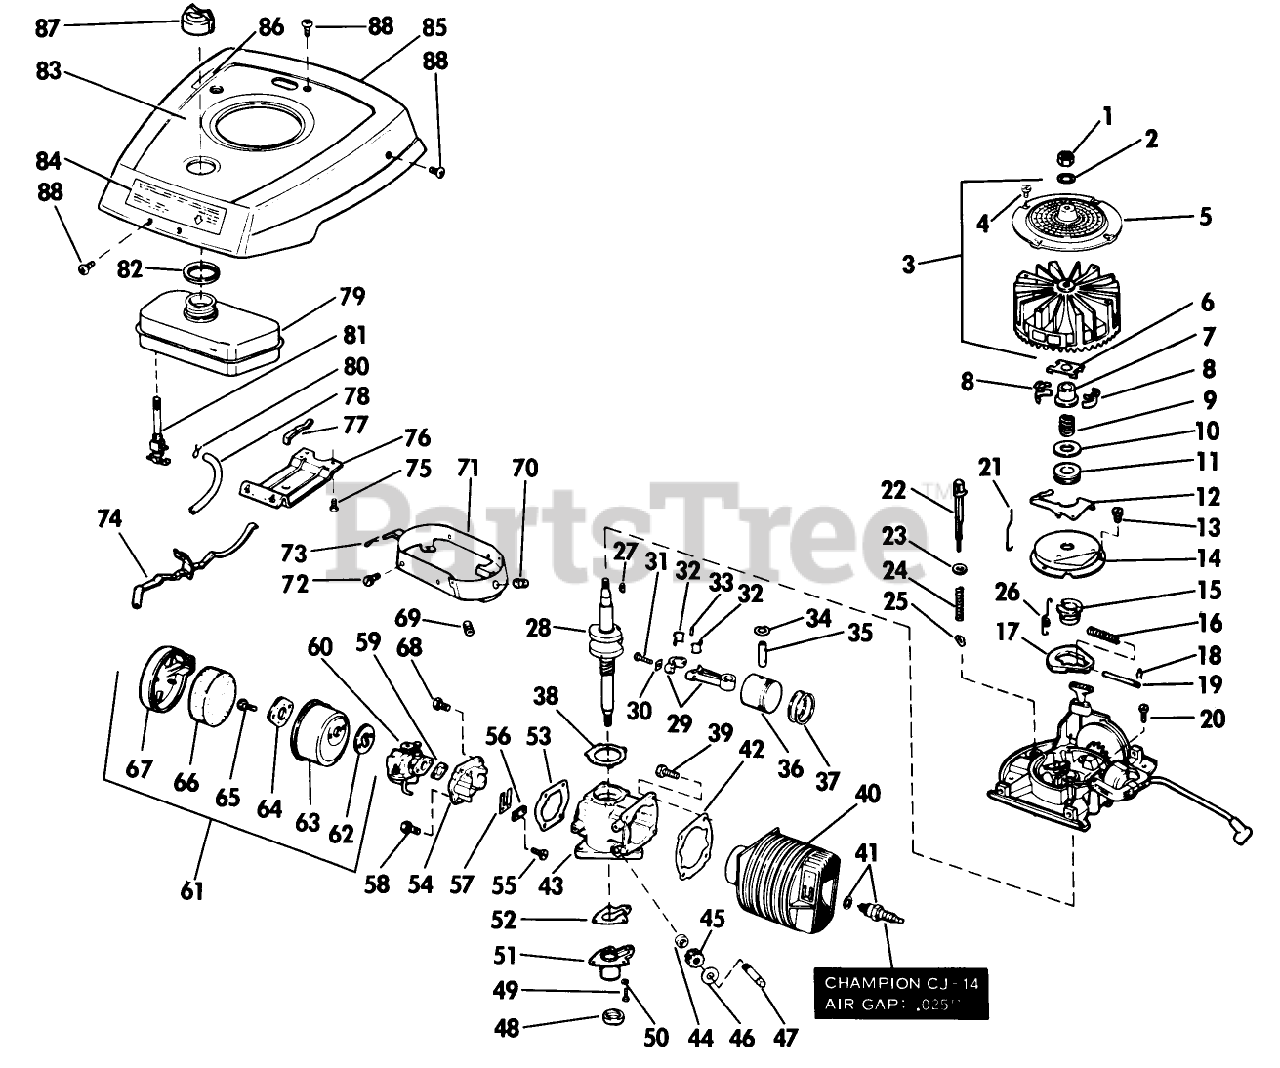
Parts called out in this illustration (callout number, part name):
3	Flywheel Screen Assy.
4	SCREW F
7	COLLAR S
9	SPRING S
11	THRUST COLLAR S
12	LEVER-GOVERNOR S
13	SCREW S
14	DUST COVER S
15	SPARK ADV. S
16	SPARK ADV. SPRING S
17	FLYWEIGHT S
18	SPARK ADJ. SPRING
19	PIN,SPARK ADV. S
24	SPRING S
32	LINER ASM
34	RING-RETAINING
38	GASKET S
41	Spark Plug Gasket
42	GASKET S
45	GEAR, DR SHAFT S
46	THRUST WASHER
51	GEAR COVER S
52	GASKET-CVR S
53	GASKET S
54	REED PLATE AY. S
56	PLATE-BACKUP, REED
58	SCREW S
59	GASKET S
62	GASKET S
63	FILTER CHAMBER S
65	SCREW S
66	AIR FIL.ELEM S
67	CHAMBER AY S
68	SCREW S
70	NUT-CLIP
72	SCREW S
75	SCREW S
78	GAS LINE
80	CLAMP - HOSE S
81	VALVE&SCREEN SM
88	SCREW S
